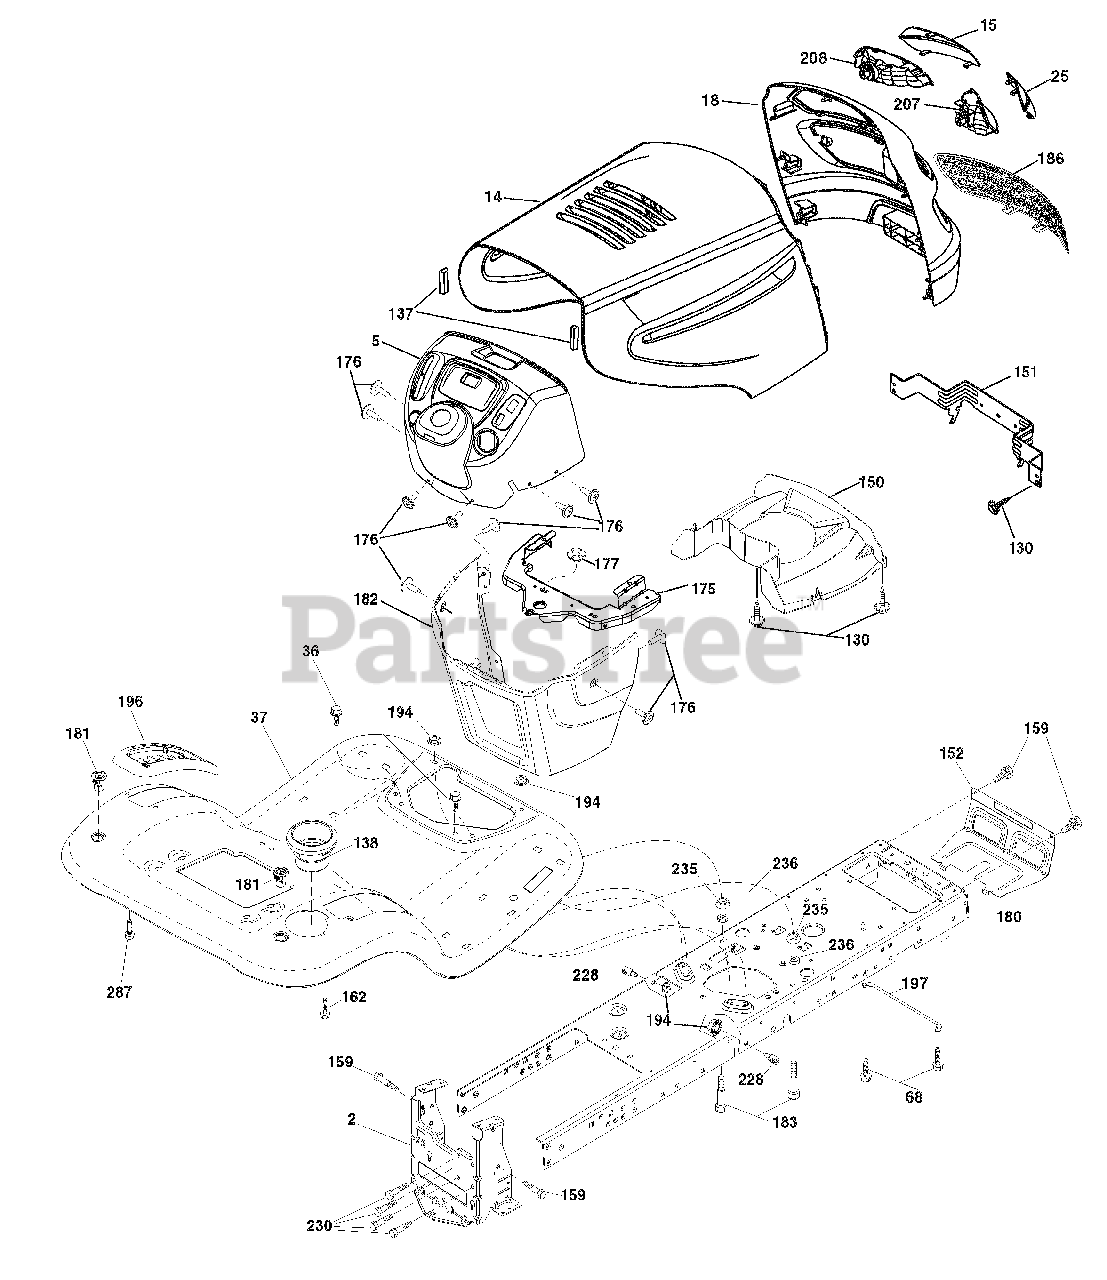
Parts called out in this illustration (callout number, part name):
2	Drawbar
5	Dash
14	Hood
15	Lens Grille LH
18	Grille
25	Lens Grille RH
36	Screw 5/16-18 x 3/4
37	Fender
68	Screw Thdrol 5/16-18 x 1/2
130	Screw #10 x 0.750 ROS Thread
137	Bumper Hood
138	Cupholder
150	Duct Heat Hood
151	Bracket Pivot
152	Shield Browning/Debris
159	Screw Hexwsh Thdrol 3/8-16 x 3/4
162	Screw Hex Wsh Hi-Lo 1/4 x 1/2
175	Crossmember
176	Screw 10-24 x 5/8 Wshd Qdrx
177	Bushing Steering
181	Bushing Mtg. Fender Crgo.
182	Dash Lower
183	Bolt Fin Hex 5/16-18 x 1-1/4
186	Insert Grille
194	Nut Lock Hex Flange 5/16-18
196	Console Asm. Deck Lift
197	Rod Pivot Chassis
207	Bezel Grille RH
208	Bezel Grille LH
228	Stud Fastener
230	Bolt Shoulder 5/16-18
235	Spacer Fender
236	Nut center Lock 5/16-18
287	Screw Hex Washead 1/4-20 x 3/8
